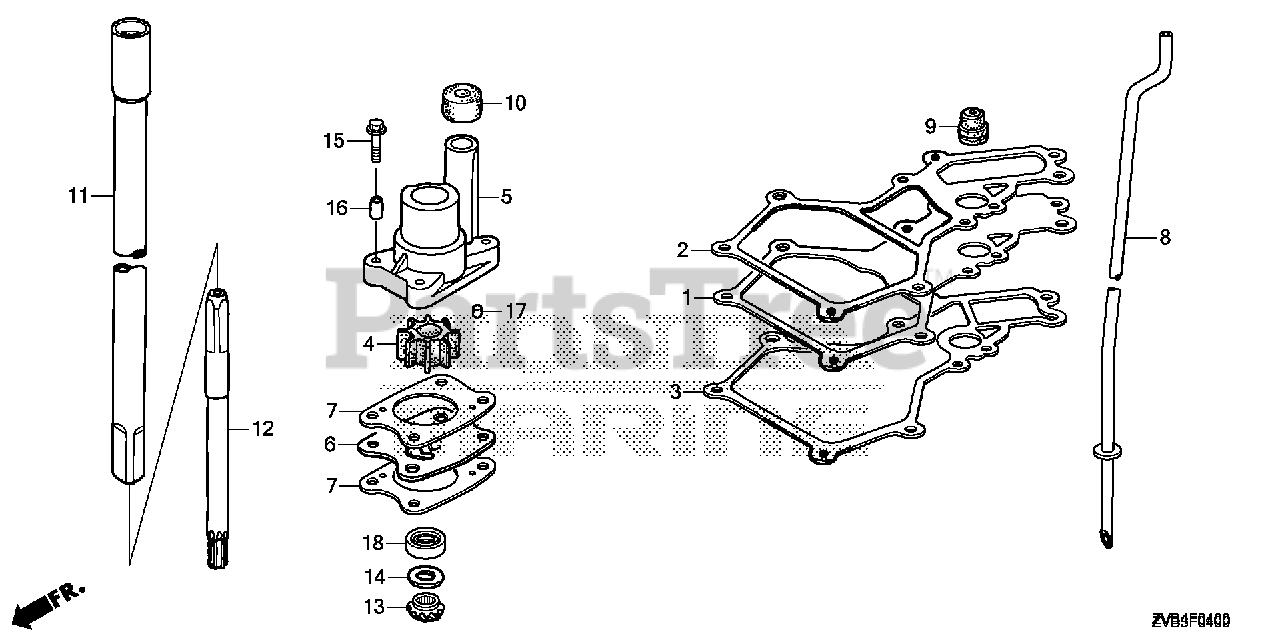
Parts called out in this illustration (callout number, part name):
1	PLATE, EX. CHAMBER
2	GASKET, EX. CHAMBER (UPPER)
3	GASKET, EX. CHAMBER (LOWER)
4	IMPELLER, PUMP
5	HOUSING, IMPELLER
6	COVER, IMPELLER
7	GASKET, IMPELLER
8	TUBE, WATER (L)
9	GROMMET, WATER TUBE
10	RING, WATER TUBE SEAL
11	SHAFT, VERTICAL (L)
12	SHAFT, PINION
13	GEAR, PINION
15	BOLT-WASHER (6X29)
16	COLLAR B, DISTANCE
17	ROLLER (4X10)
18	SEAL, WATER (13MM) (ARAI)
